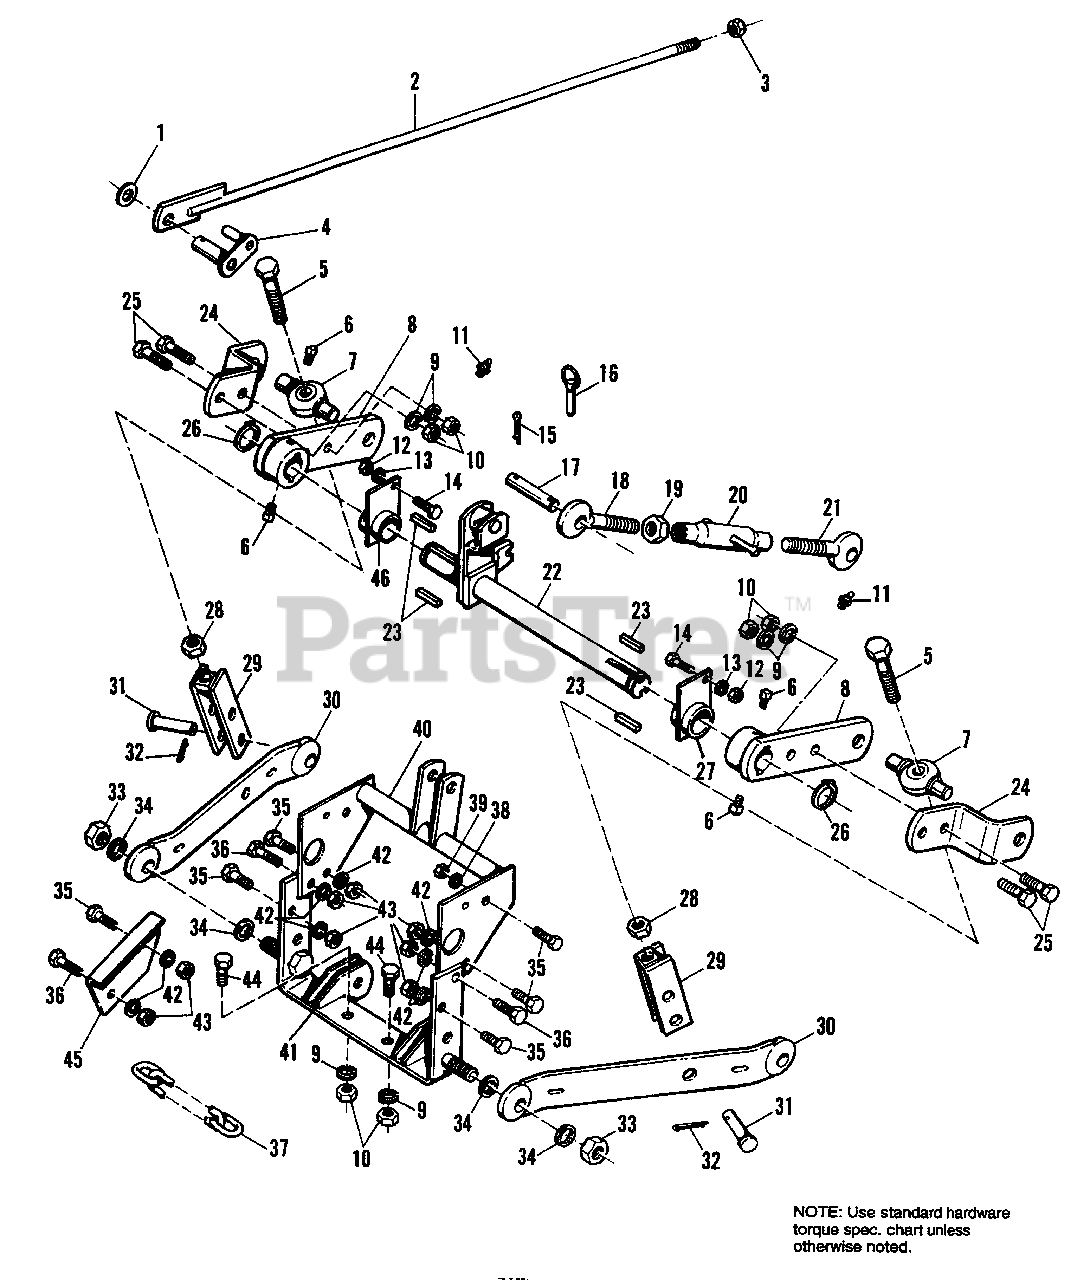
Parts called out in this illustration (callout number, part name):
1	WASHER, Plain, 41/64 x 1-1/4 x 1/16
2	ROD ASSY., Lift
3	NUT, Hex, Lock, 1/2-13
4	PIN ASSY., Cylinder
5	CAPSCREW, Hex Hd., 5/8-11 x 4
6	SETSCREW, Sq. Hd., 3/8-16 x 3/4
7	BALL SOCKET ASSY.
8	LIFT LINK ASSY.
9	LOCKWASHER, 1/2
10	NUT, Hex, 1/2-13
11	FITTING, Lub.
12	NUT, Hex, 5/16-18
13	LOCKWASHER, 5/16
14	CAPSCREW, Hex Hd., 5/16-18 x 1-1/4
15	PIN, Cotter, 1/4 x 1-1/2
16	PIN & RING ASSY., 1/4" Dia.
18	STUD ASSY., Adjust. R.H.
19	NUT, Hex, Jam, 3/4-10
20	TUBE ASSY., Upper Link
21	STUD ASSY., Adjust. L.H.
22	LIFT SHAFT ASSY.
23	KEY, Sq. 5/16 x 1-1/2
24	BRACKET, Lift Link
25	CAPSCREW, Hex Hd., 1/2-13 x 1-3/4
26	RING, Retaining, Ext., 1-1/4 Dia.
27	BEARING ASSY., L.H.
28	NUT, Hex, Lock, Jam, 5/8-11
29	CLEVIS ASSY.
30	LINK ASSY., Lower
31	PIN, Clevis, 5/8 x 2-1/4
32	PIN, Cotter, 1/8 x 1
33	NUT, Hex, Centerlock, 3/4-10
34	WASHER, 1 x 3/4 x 5/64
35	CAPSCREW, Hex Hd., 7/16-14 x 1-1/4
36	CAPSCREW, Hex Hd., 7/16-14 x 1 1/2
37	CHAIN, Sway, 22-5/8
38	WASHER, Plain, 7/16
39	NUT, Hex, Whizlock, 7/16-14
40	LINK ASSY., Upper
41	BRACKET ASSY., Hitch
42	LOCKWASHER, 7/16
43	NUT, Hex Hd., 7/16-14
44	CAPSCREW, Hex Hd., 1/2-13 x 2
45	BRACKET, Upper Stop
46	BEARING ASSY., R.H.
